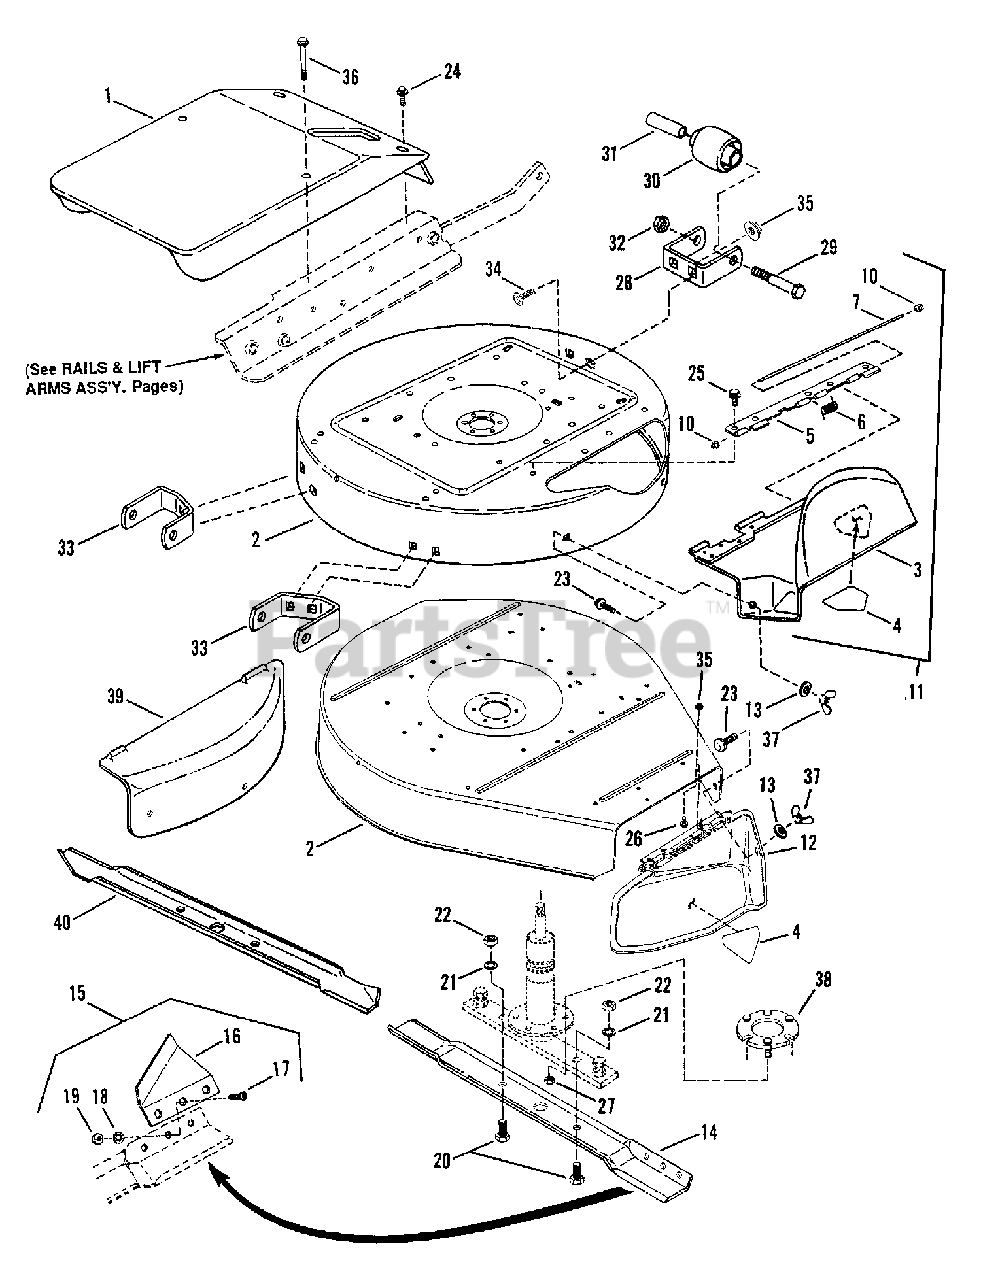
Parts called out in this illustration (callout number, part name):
1	COVER, Spindle
2	25" DECK (Includes decals)
2	28" DECK (Includes decals)
2	30" DECK (Includes decals & deflector)
2	33" DECK (Includes decals)
3	DEFLECTOR, Discharge (25" Deck)
3	DEFLECTOR, Discharge (28" & 33" Deck)
4	DECAL, Danger (Cut Finger)
5	HINGE, Deflector
6	SPRING, Hinge
7	PIN, Hinge
10	NUT, Push
11	ASSEMBLY, Discharge (25" Deck)
11	ASSEMBLY, Discharge (28" & 33" Deck)
12	DEFLECTOR, Discharge (30" Deck)
13	WASHER, 5/16 Flat
14	25" BLADE
14	28" BLADE
14	30" BLADE
14	33" BLADE
15	AIR LIFT KIT, Hi-Vac
16	AIR LIFT, Hi-Vac (3 hole)
17	SCREW, 5/16-24 x 11/16" Machine
18	WASHER, 5/16-24 Internal Tooth Lock
19	NUT, 5/16-24 Hex
20	SCREW, 1/2-20 x 1" Hex Head Cap
21	WASHER, 1/2 Internal Tooth Lock
22	NUT, 1/2-20 Hex Jam
23	BOLT, 5/16-18 x 3/4" Short Neck Carriage
24	SCREW, 1/4-20 x 5/8" Self-Tapping
25	SCREW, 5/16-18 x 1/2" Self-Tapping
26	BOLT, 5/16-18 x 1/2" Hex Flange Lock
27	NUT, 3/8-16 Hex Flange Lock
28	BRACKET, Gage Wheel (Front)
29	SCREW, 3/8-24 x 3-3/4" Hex Head Cap
30	WHEEL, Gage
31	SPACER
32	NUT, 3/8-24 Hex Lock
33	BRACKET, Gage Wheel (Rear)
34	BOLT, 5/16-18 x 1/2" Short Neck Carriage
35	NUT, 5/16-18 Hex Flange Lock
36	SCREW, 1/4-20 x 3/-1/2" Self-Tapping
37	NUT, 5/16-18 Wing
38	RING, Spindle
39	COVER, 25" Mulcher
39	COVER, 28" Mulcher
39	COVER, 33" Mulcher
40	BLADE, 25" Mulcher
40	BLADE, 28" Mulcher
40	BLADE, 33" Mulcher
